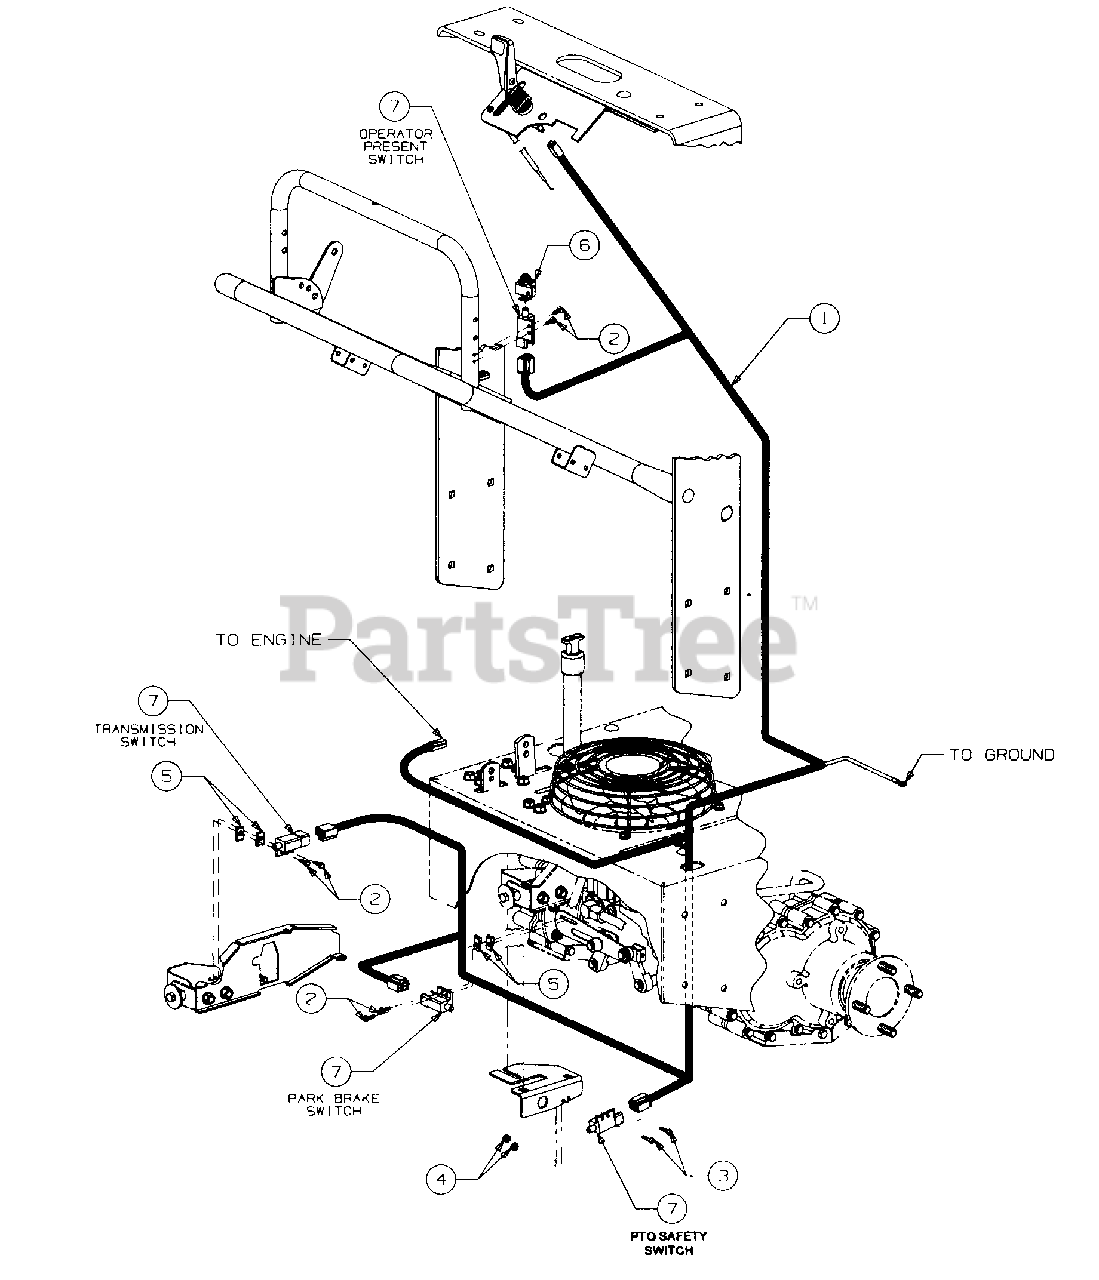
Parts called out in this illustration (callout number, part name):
2	Screw, Hex Wash Hd Tapp, #10-24 X .62 Lg
3	Screw, Pan Hd, #10-24 X .75 Lg
4	Nut, Hex Nylock, #10-24
5	Nut, Speed
6	Cover, Protective
7	Switch, Double Poled Plunger
